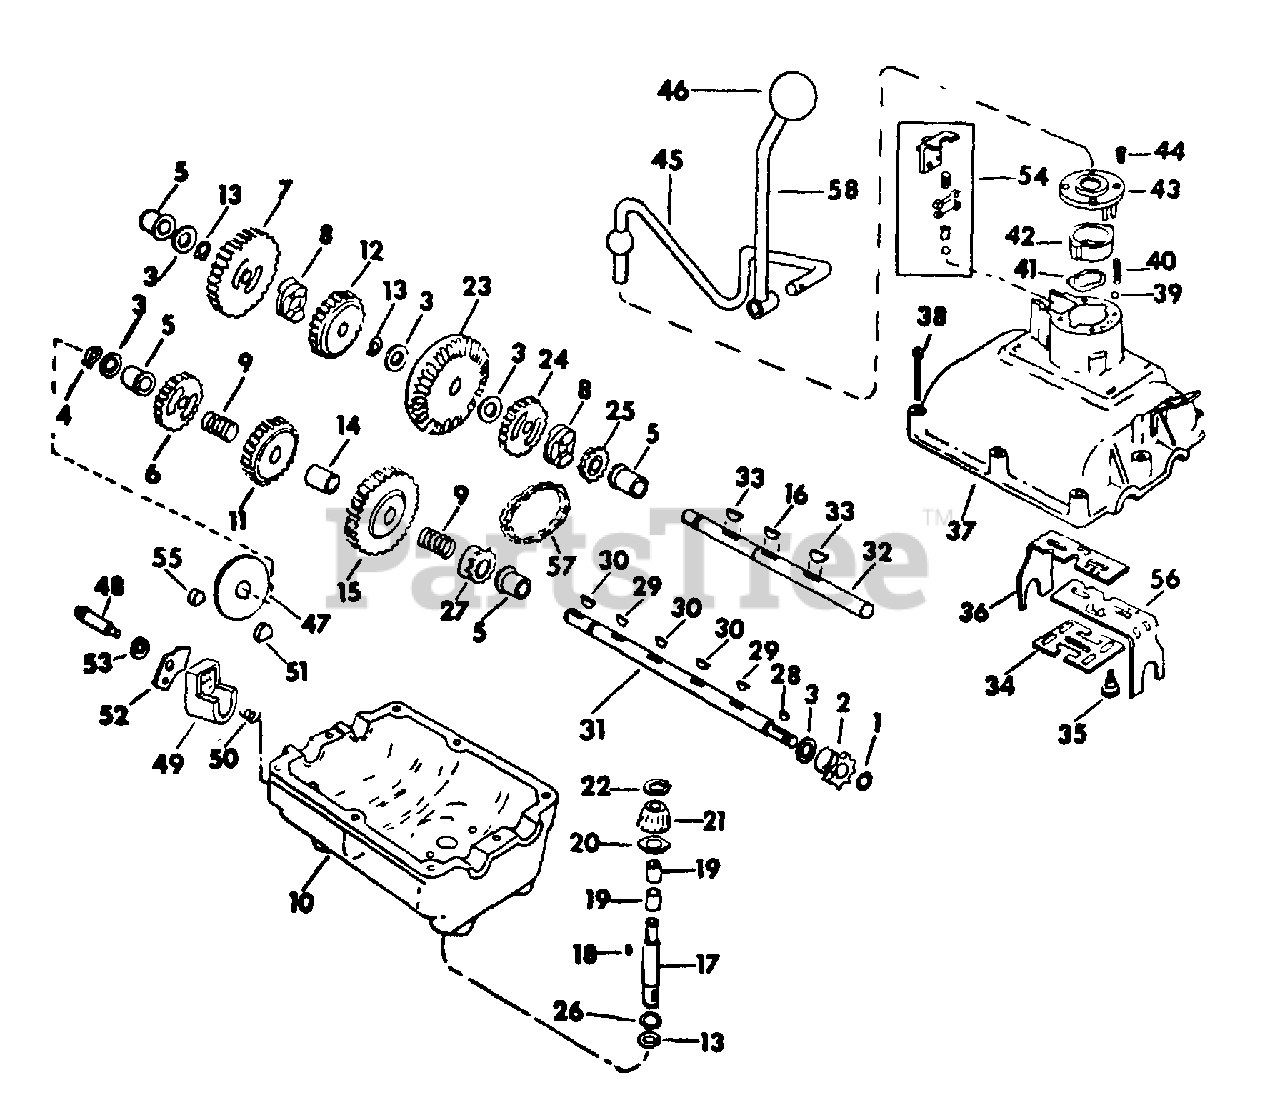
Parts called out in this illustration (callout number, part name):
1	RING, 461 INV EXT RET
2	SPROCKET, 8 T
3	WASHER, PLAIN .030
4	RING, RETAINING
5	BEARING, FLANGE
6	GEAR, SPUR -20 T
7	GEAR W/SPACER SPUR -30T
8	COLLAR, CLUTCH
9	SPRING, COMPRESSION
10	HOUSING, LOWER
11	GEAR W/SPACER, SPUR -25 T
12	GEAR W/SPACER, SPUR -25 T
13	RING, 579 EXT RET
15	GEAR, SPUR -30 T
16	KEY, 3/16 X 3/4 WOODRUFF 9
17	SHAFT KIT, INPUT
18	KEY, 3/32 X 1/2 WOODRUFF 2
19	BEARING, NEEDLE
20	WASHER, THRUST .093
21	PINION, BEVEL -16 T
22	RING, RETAINING
23	GEAR, BEVEL -42 T
24	GEAR, SPUR -20 T
25	SPROCKET, SPECIAL -12 T
26	WASHER, .656 X 1.000 X .054 PLN
27	SPROCKET, SPECIAL -12 T
28	KEY, WOODRUFF NO. 4 SPECIAL
29	KEY, 1/8 X 1/2 WOODRUFF 3
30	KEY, 3/16 X 5/8 WOODRUFF 61
31	SHAFT, OUTPUT
32	SHAFT WIRING, IH-269174-R1, DRIVE
33	KEY, HI-PRO SPECIAL
34	PLATE, LOCK-OUT
35	SCREW, SHOULDER
36	FORK, SHIFTER LH
37	HOUSING, UPPER
38	SCREW, TAPPING
39	BALL, 3/16 CR-STL DETENT
40	SPRING, DETENT
41	WASHER, WAVE
42	INSERT, NYLON
43	COVER, NYLON
44	SCREW, 10-24 X 1/2 C-Z CR-REC-PAN-HD TAP
45	HANDLE ASSY, SHIFTER
45	KNOB, SHIFTER
46	KNOB, SHIFTER
48	BOLT, SHOULDER
50	SPRING, COMPRESSION
51	PUCK, FRICTION
52	LEVER ASSY, ACTUATING RH
53	WASHER, PLAIN .015
53	WASHER, PLAIN .006
54	KIT, SWITCH ASSY
55	PUCK, FRICTION
56	FORK, SHIFTER RH
57	CHAIN, ROLLER
58	HANDLE ASSY, SHIFT
